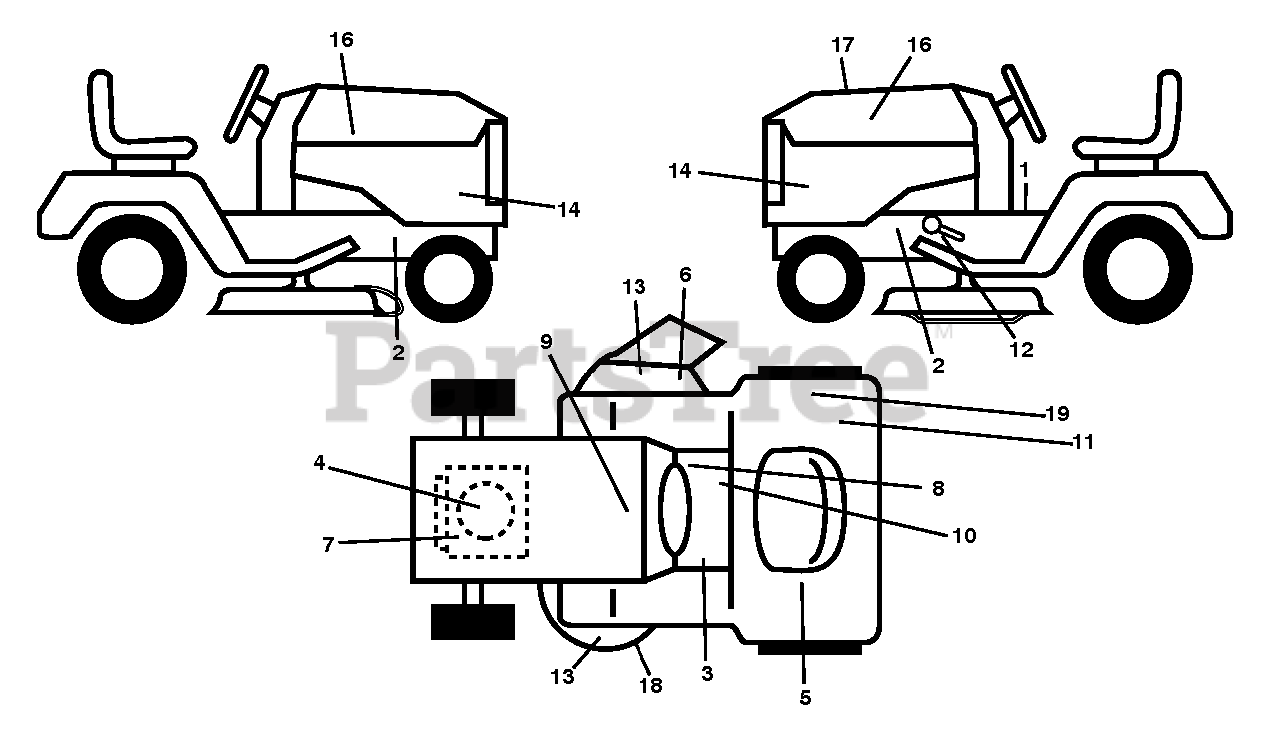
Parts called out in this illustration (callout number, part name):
1	DECAL.READ.OWN.MAN.SYMBOL.LT
2	DECAL.CHASSIS.HOT.MUFFLER
3	DECAL.FNDR.SDLE.BRAKE.CLUTCH.6
4	DECAL.ENG.BS.ENDUR.27HP.382139
5	DECAL.RESERVEFUELSELCTR.ENG
6	DECAL, DECK DEFLECTOR, WARNING
7	DECAL.ENGINE.WARNING
8	DECAL.PARKING.BRAKE.SADDLE.LT
9	DECAL BTRY SYMBOLS
10	DECAL.FWD/REV.PEDAL.SYMBOL
11	DECAL.TICKMARK.6MIL.AUSTRALIA
12	DECAL.PEDAL.HUSQ.CROWN
13	DECAL.DECK.6MIL.EURO.NOSTEP
14	DECAL.SDPNL.GT2.SET.GTH3052TDF
15	DECAL.DECK.6MIL./DEF.SHLD.WARN
16	DECAL.BADGE.170MM.TEXTLOGO.
17	DECAL.RPL.BSM49.ENDR.TGB.52F.
18	DECAL.MOWER.SCH.48/54.PREM
19	DECAL.80.DBA.AUSTRALIA
